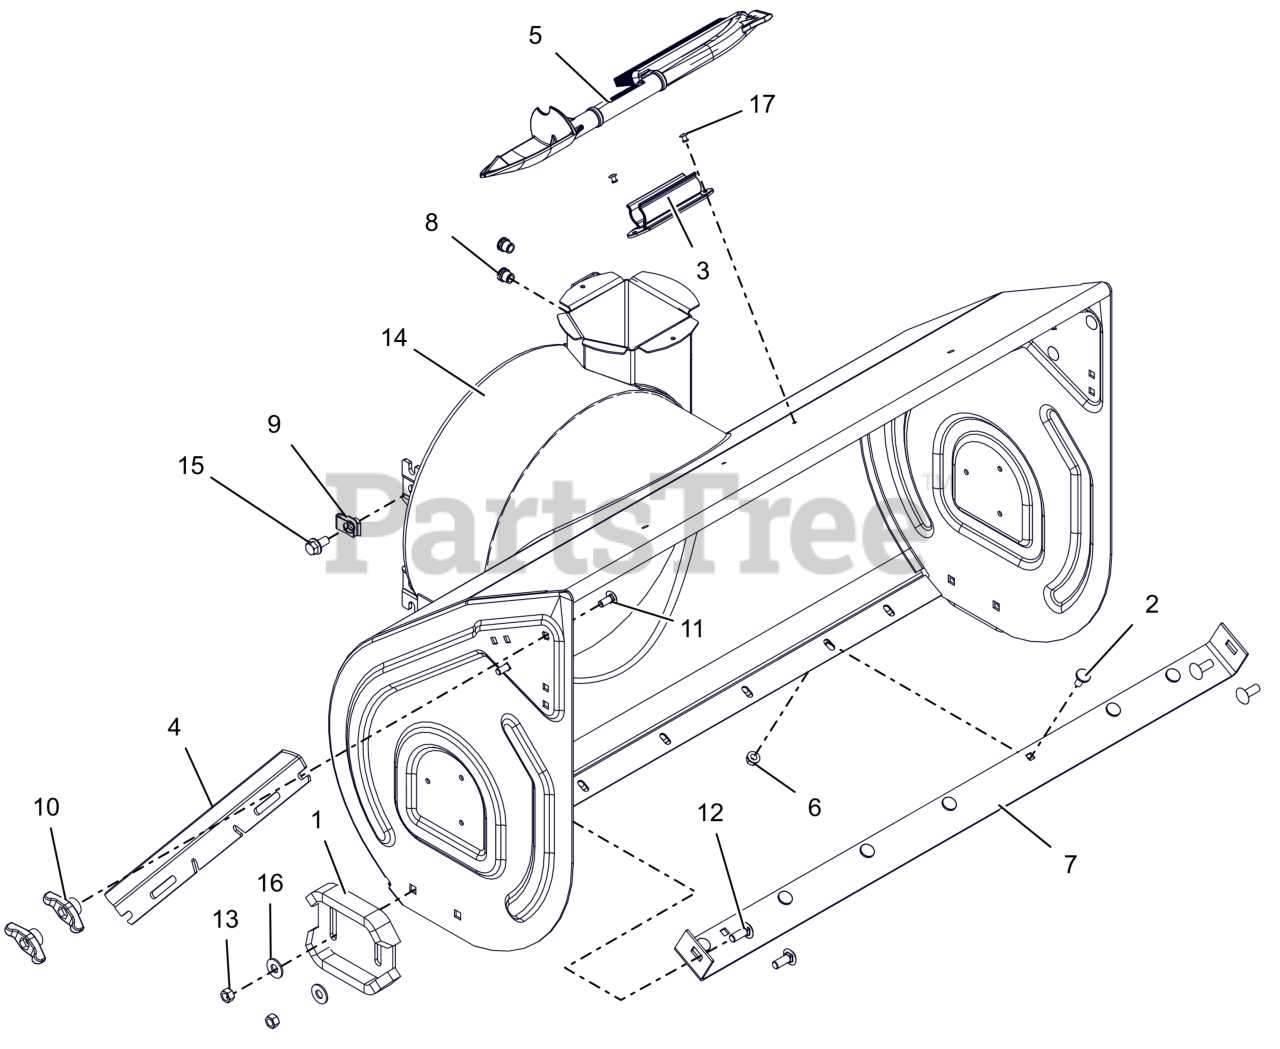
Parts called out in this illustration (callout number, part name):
1	RUNNER, SKID SHOE
2	BOLT, MODIFIED HEAD CARRIAGE
3	MOUNT, SNOW CLEAN OUT
4	CUTTER, DRIFT
5	DEVICE, SNOW CLEAN OUT W/BRUSH
6	NUT-LK-TOP-FLG .312-18 GF ZCC
7	BLADE, SCRAPER-36"
8	NUT,THD,INSERT .38-16 ZC120
9	NUT-RTNR .375-16X.37
10	KNOB,WING .31-18 UNC NYL/TALC
11	BLT, RHSSN.31-18X.750 G5 ZCC
12	BLT,RHSSN .38-16X1.00 G5 ZCC
13	NUT-LK-CTR .38-16 ZC120
14	BLOWER HOUSING W/DECAL 36"
16	WSHR,FLT .438X1.00X.083 ZCC
17	RVT, POP .1875 ZCC
